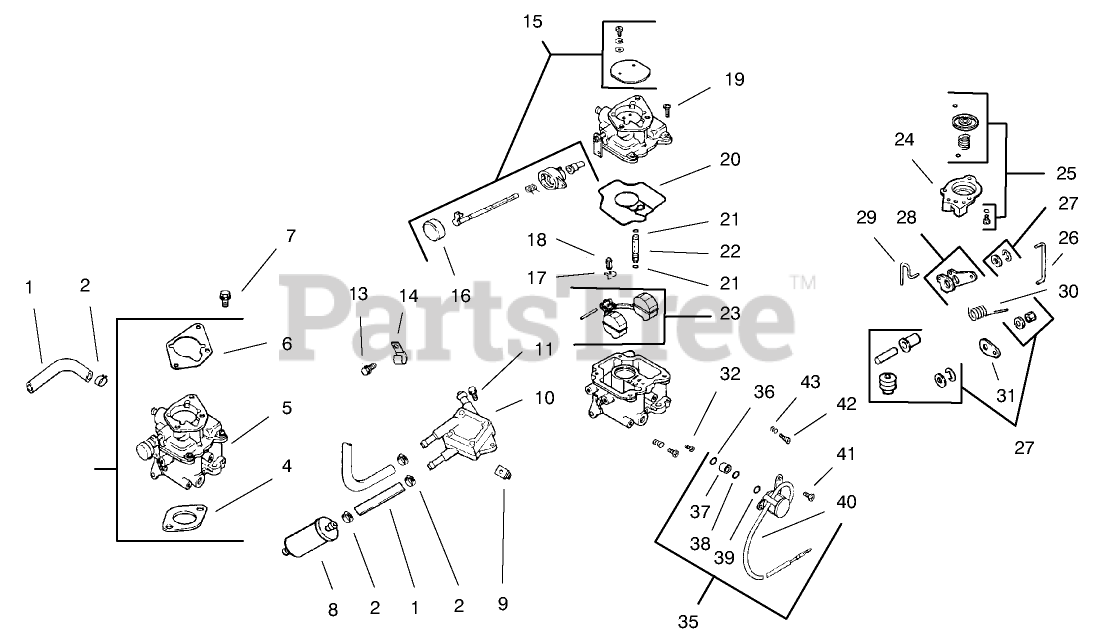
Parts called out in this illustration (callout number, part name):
1	Line fuel
2	Clamp
3	Kit, carburetor w/gasket (Includes 4-6)
4	Gasket
5	Carburetor assembly (Includes 15-43 and carburetor repair kit 24 757 03)(For information only not available separately)
6	Gasket
7	Screw
8	Filter-Fuel
9	Nut
10	Pump-Fuel
11	Screw
12	Line, fuel
13	Screw
14	Clip-Cable
15	Kit, choke repair (Includes 16)
16	Cap-Choke Lever
17	Clip, cable
18	Valve-Inlet Needle
19	Screw
20	Gasket-Body,Carburetor
21	"O"Ring
22	Jet-Slow
23	Roat Repair Kit
24	Housing-Pump
25	Kit repair-accelerator pump
26	Linkage-Rod
27	Kit repair-accelerator pump diagram
28	Lever-Rod
29	Linkage-Rod
30	Spring-Linkage
31	Lever-Linkage
32	Jet-Main
33	Spring-Idle Adj.
34	Needle, idle
35	Kit, solenoid assembly (Includes 36-41)
36	O-Ring
37	Seat-Solenoid
38	O-Ring
39	O-Ring
40	Solenoid
41	Screw
42	Screw, idle adjusting
43	Spring-Idle Speed Adj.
